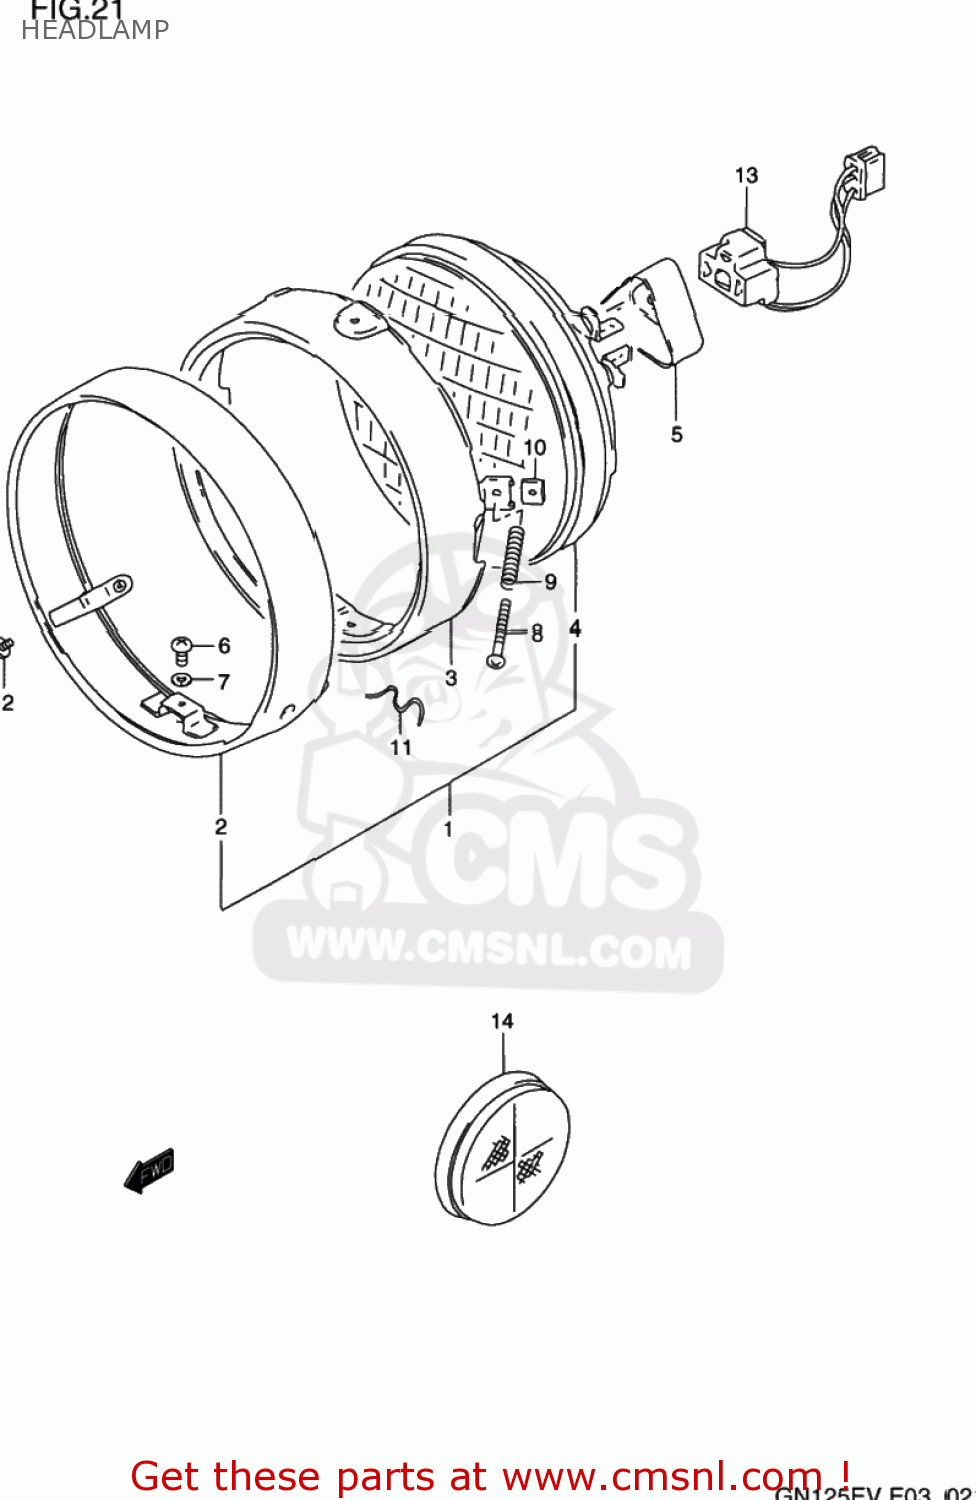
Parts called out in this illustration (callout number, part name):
1	LAMP ASSEMBLY,HEAD
2	RIM
3	RETAINER
4	LAMP UNIT
5	COVER
6	SCREW
7	WASHER,LOCK
8	SCREW
9	SPRING
10	NUT
11	SPRING,HEAD LAMP UNIT
12	SCREW
13	LEAD WIRE,HEADLAMP
14	REFLEX REFLECTOR,RR
